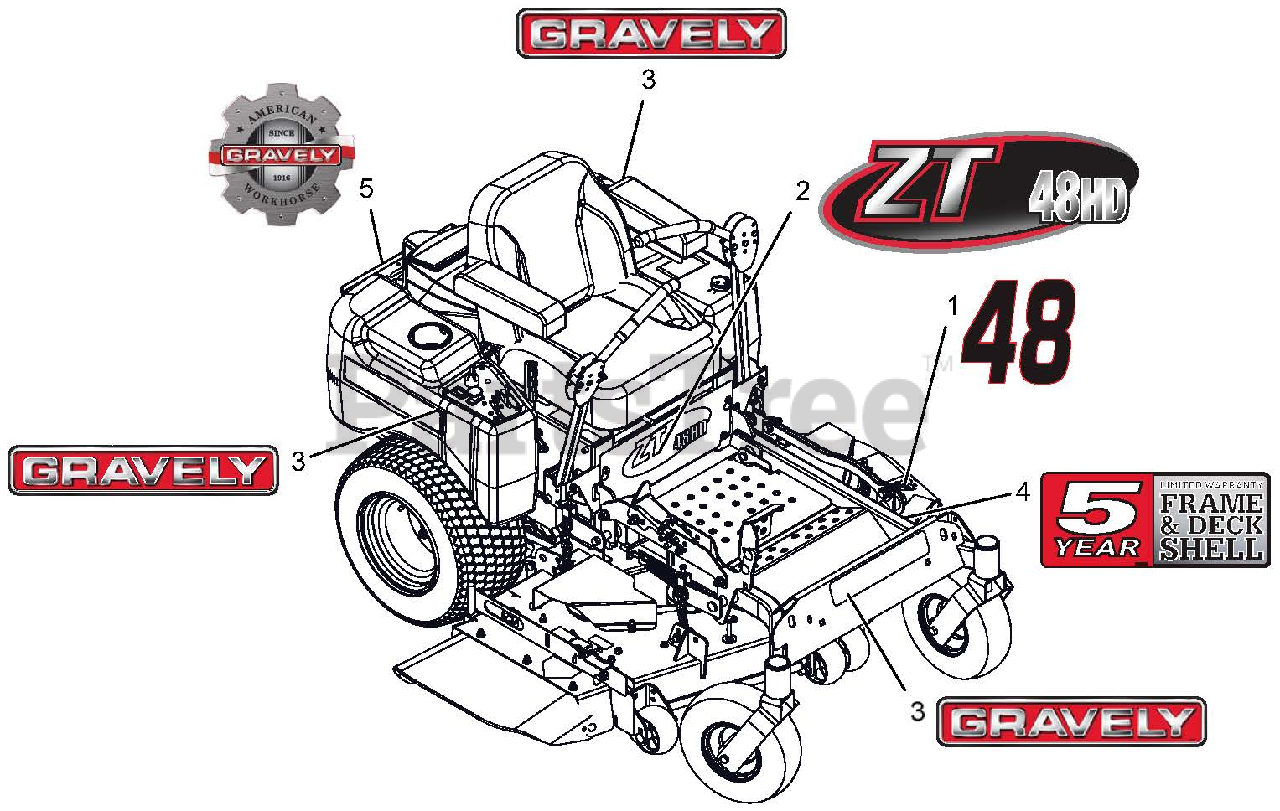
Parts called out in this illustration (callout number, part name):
1	DECAL, 48"
2	DECAL, 48HD
3	DECAL, FUEL TANK-GRAVELY
4	DECAL, DECK WARRANTY-FAB GRAVELY
5	DECAL, GRAVELY HERITAGE-SMALL
